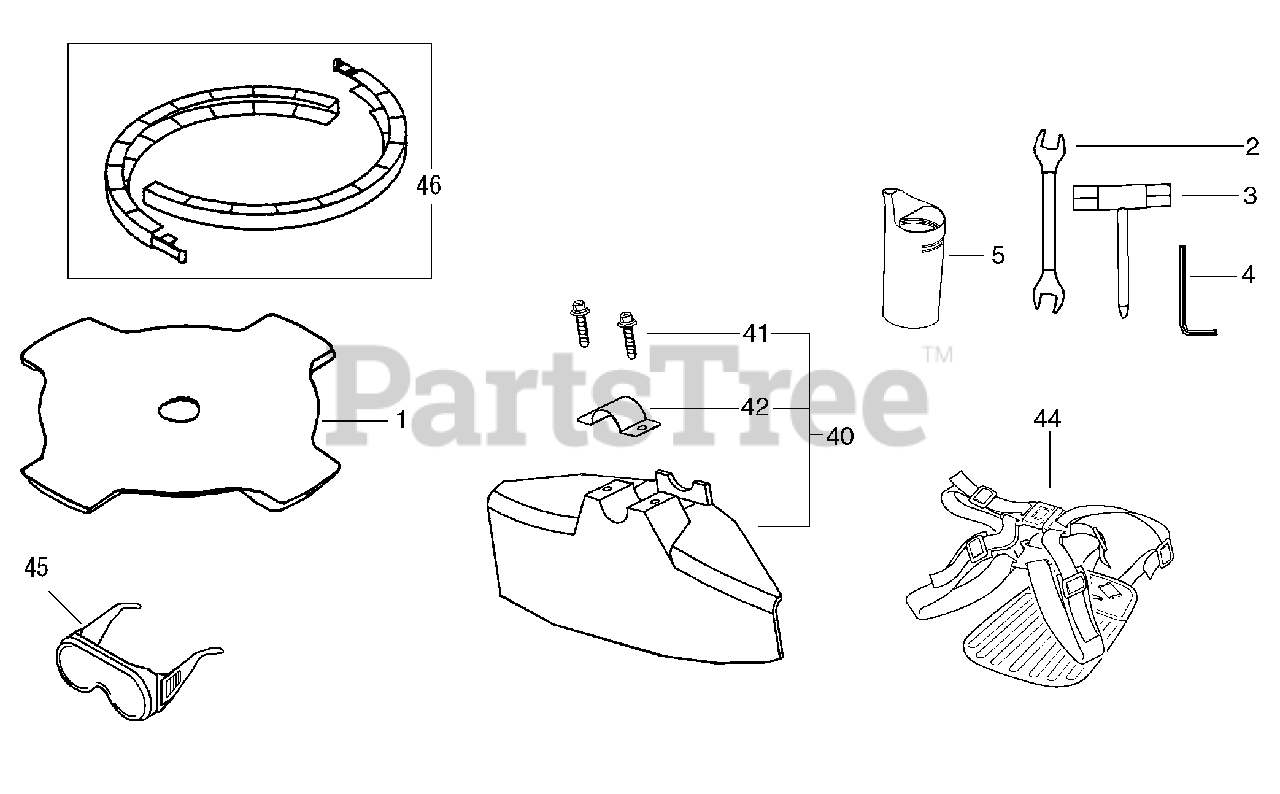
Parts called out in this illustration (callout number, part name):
1	BLADE, BRUSHCUTTER
2	SPANNER - 8X10mm
3	T-WRENCH - 17X19mm
4	HEX KEY - 5mm
5	MIXER, FUEL
40	DEBRIS SHIELD ASSY
41	BOLT - 6X28
44	HARNESS ASSY
45	GOGGLES
46	COVER, BLADE
